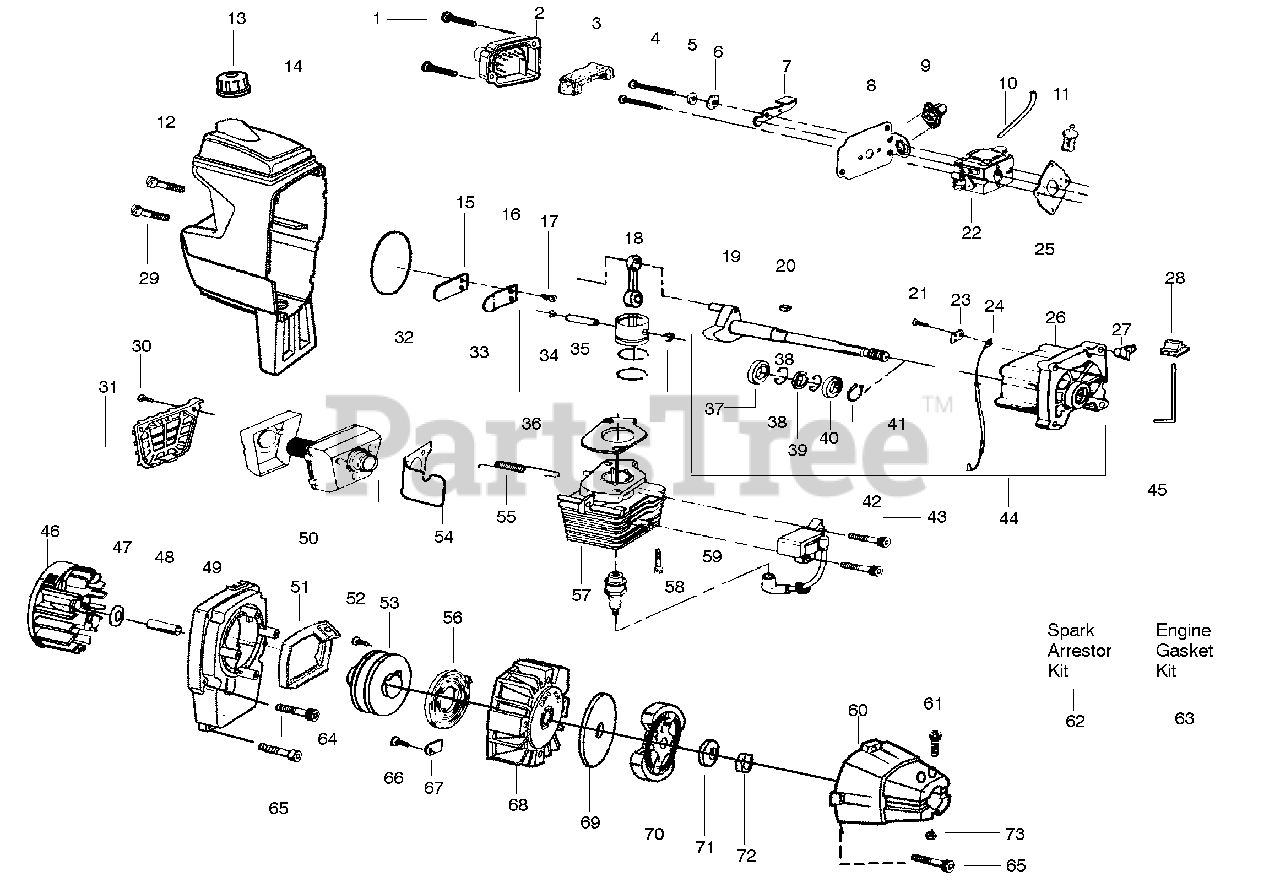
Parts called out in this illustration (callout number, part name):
2	Cover-Air Filter
3	Foam-Air Filter
5	Spacer-Choke
7	Shutter-Choke
8	Plate-Choke
9	Assy-Bulb
10	Kit-Fuel Line
11	Assy-Fuel Pick-up
13	Assy-Fuel Cap.
14	Assy-Shroud/Tank
15	Valve-Reed
16	Stop-Reed Valve
18	Assy-Connecting Rod
19	Assy-Crankshaft
20	Key-Flywheel
22	Kit-Carburetor Ass'y., (WT-583)
22	Kit-Carburetor Ass'y., (WT-629)
23	Insulator-Switch
24	Assy-Leadwire
25	Gasket-Carb.(kit)
26	Assy-Crankcase
27	Ramp-Switch
28	Cover-Switch
31	Guard-Muffler
32	O-ring-C'case(kit)
33	Kit-Piston
34	Piston Pin Retainer
35	Piston Ring (2)
36	Gasket-Cyl. (kit)
37	Bearing-Inner
38	Ring-Retaining
39	Seal-Crankshaft
40	Bearing-Outer
41	Retaining Ring-C'shaft
42	Module-Ignition
44	Assy-C'case/C'shaft
45	Spring-Switch
46	Assy-Flywheel
48	Spacer-Clutch
49	Housing-Fan
50	Kit-Muffler
51	Assy-Retainer/Eyelet
53	Kit-Starter Pulley
54	Heat Shield/Air Dam
55	Spring-Muffler
56	Spring-Starter
57	Kit-Cylinder
58	Spark Plug (RCJ-6Y)
60	Assy-Clutch Housing
62	Kit-Spark Arrestor
63	Kit-Engine Gasket
67	Retainer
68	Assy-Pulley Housing
69	Washer-Clutch
70	Kit-Clutch Ass'y.
71	Washer-Bevel
73	Locknut.
